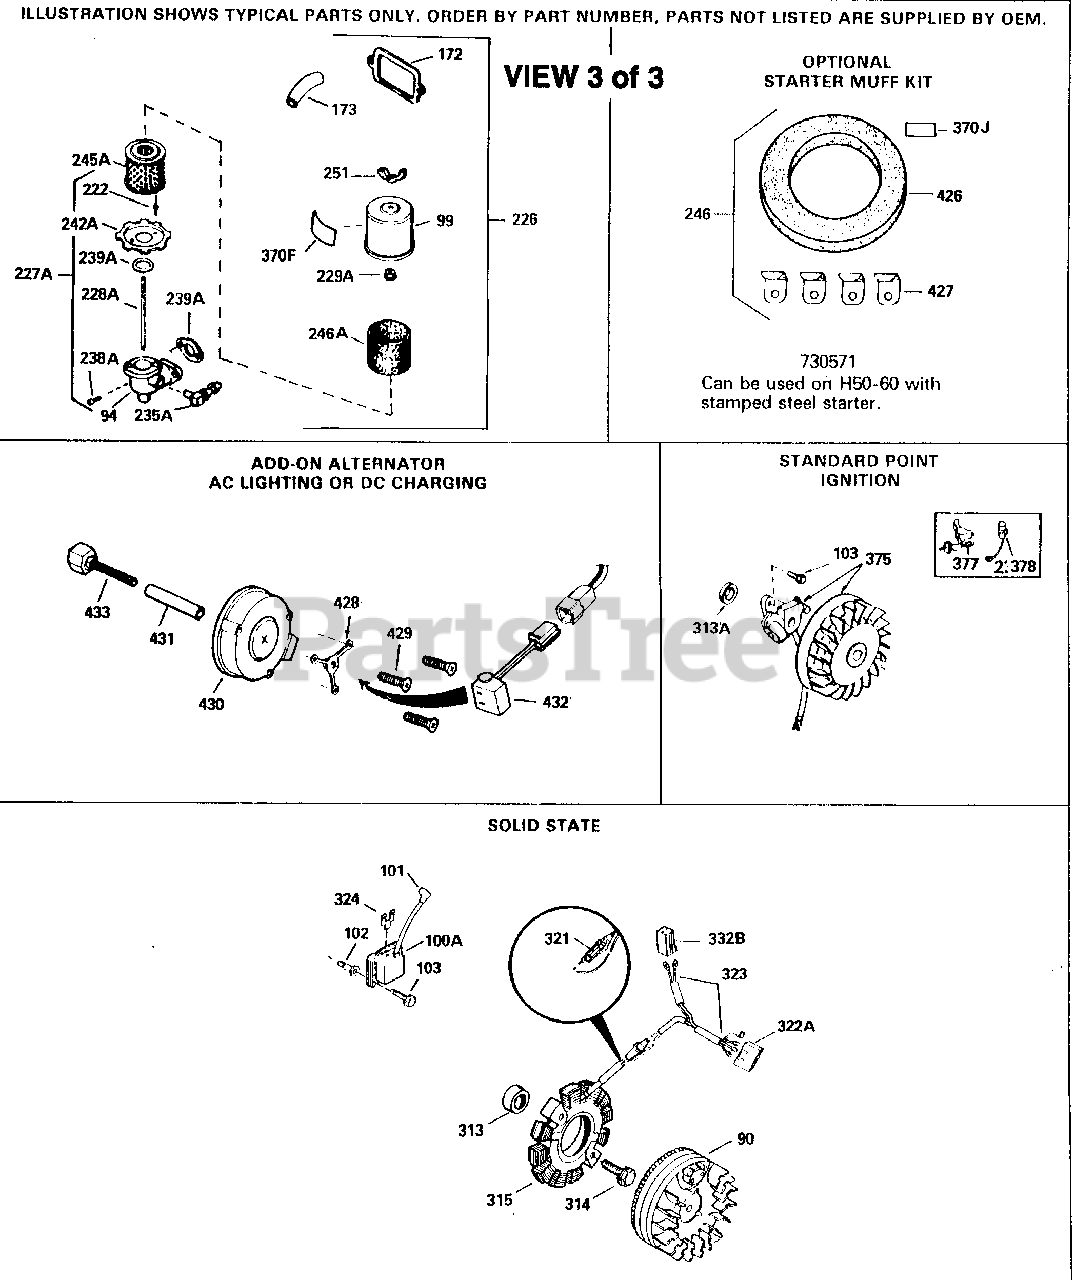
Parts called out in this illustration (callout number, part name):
19	Speed Control Spring
28	Lock Nut, 8-32
42	Ring Set (Std.)
42	Ring Set (.010" OS)
42	Ring Set (.020" OS)
90	Flywheel
101	Spark Plug Cover
102	Solid State Mounting Stud
103	Screw, Torx T-15, 10-24 x 1"
172	Valve Cover
173	Breather Tube
200	Control Bracket (Incl.19,203,204,206)
235	Breather Tube Fitting
238	Screw, 10-32 x 1/2"
238A	Screw, 10-32 x 7/8"
239	* Air Cleaner Gasket
265	Cylinder Head Cover
272	Screw, 5/16-18 x 3/4"
273	Carburetor Flange
291	Fuel Line
307	"O" Ring
310	Dipstick
